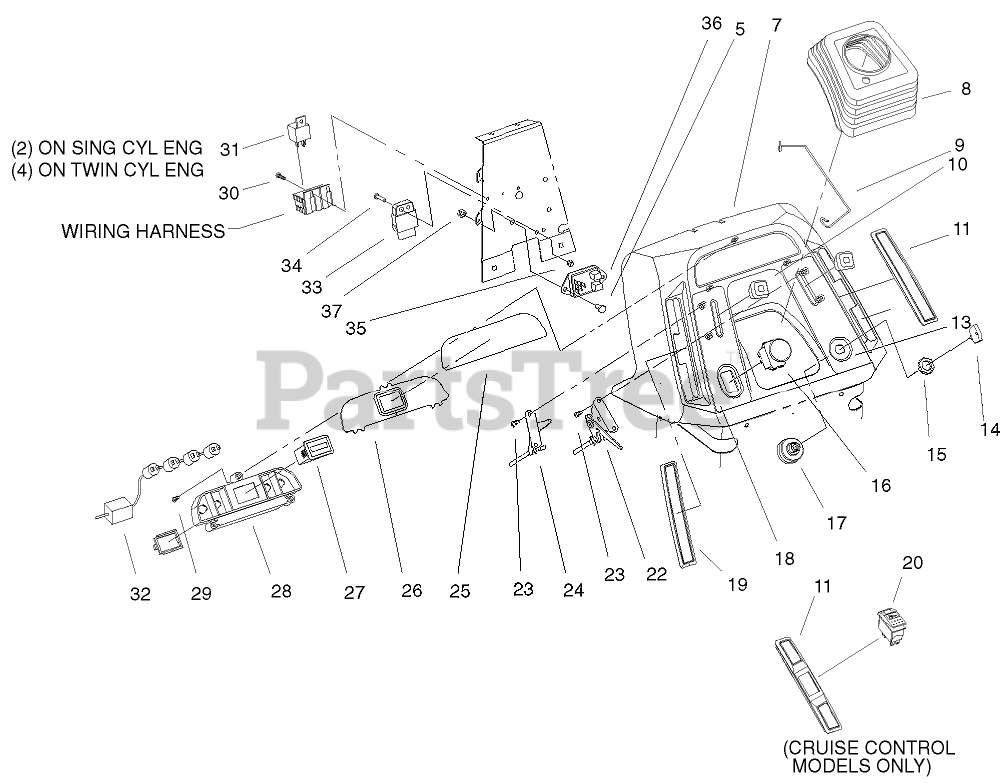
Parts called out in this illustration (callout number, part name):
5	SCREW-HH
8	BOOT-STEERING
9	CLIP-BOOT
11	Cover-RH Slot (only on: 72087)
11	Cover-RH Slot (only on: 72107)
13	Decal-Throttle/Ign (only on: 72087)
13	Decal-Dash Throt/Ign (only on: 72107)
14	KEY-IGNITION
16	SWITCH-PTO
17	SWITCH-IGNITION
18	Decal-PTO/Choke (only on: 72087)
18	Decal-Dash PTO/Choke (only on: 72107)
19	COVER-SLOT, LH
20	SWITCH-CRUISE
22	CONTROL-THROTTLE (TWIN)
24	CONTROL-CHOKE (TWIN)
25	DECAL-LENS, DASH
26	LENS-DASH
27	HOURMETER
28	HOUSING-LIGHT, INDICATOR
29	SCREW
30	SCREW-PPHTF
31	RELAY
32	HARNESS-4 LAMP
33	MODULE-LOW VOLTAGE
35	NUT-LOCK, NI
36	MODULE-CLUTCH
37	NUT-LOCK, NI
